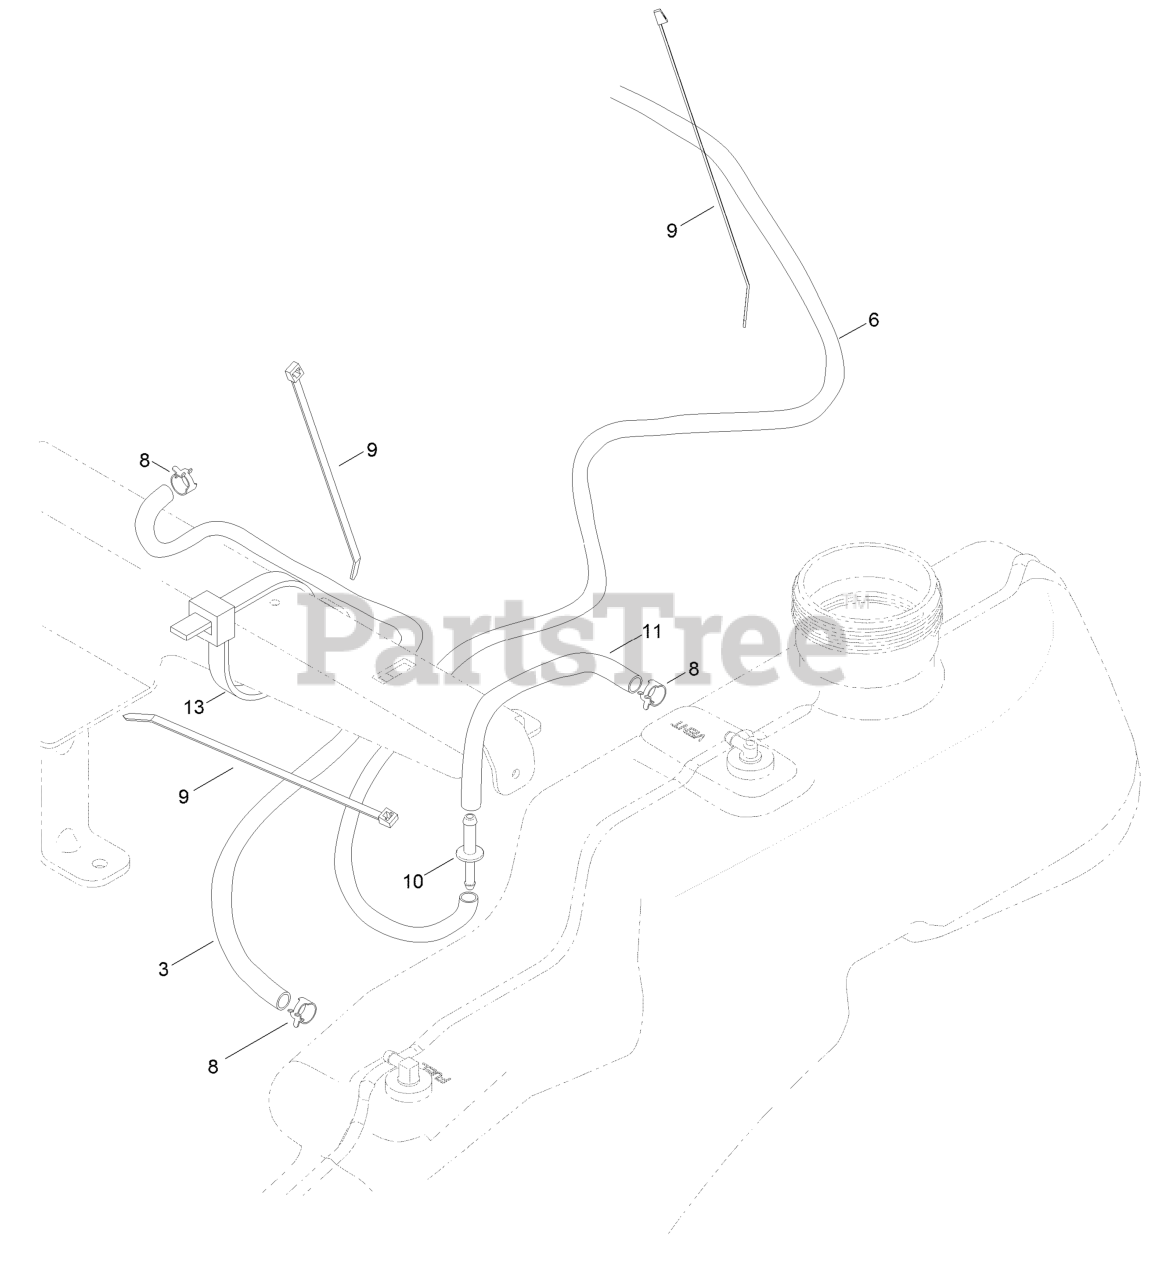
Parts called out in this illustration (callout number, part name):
3	HOSE-FUEL
6	HOSE-FUEL
8	CLAMP-HOSE
9	TIE-CABLE
10	ADAPTOR-ORIFICE
11	HOSE-FUEL
13	TIE-CABLE
